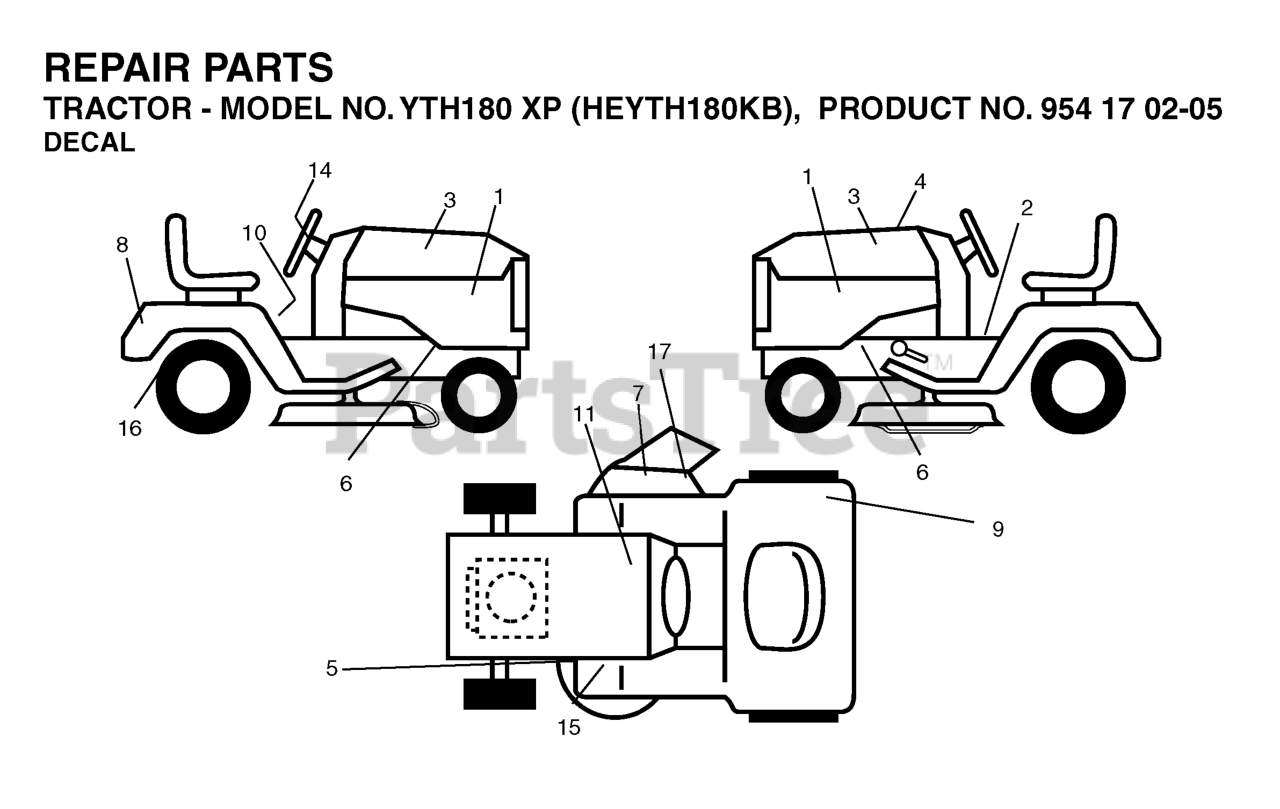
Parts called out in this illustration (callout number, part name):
1	DECAL.HOOD.HUSQVARNA.INTERNATI
2	DECAL PARK BRAKE
5	DECAL V BELT SCHEMATIC
7	DECAL.INTERNATIONL.CUTFINGER
9	Decal, Fender 100 DB/CE
10	DECAL READ OWNER'S MAN SYMS
11	DECAL BTRY SYMBOLS
14	DECAL.STEERING.HUSQ.BLUE
15	DECAL
16	DECAL
17	DECAL DECK "B" 42"
